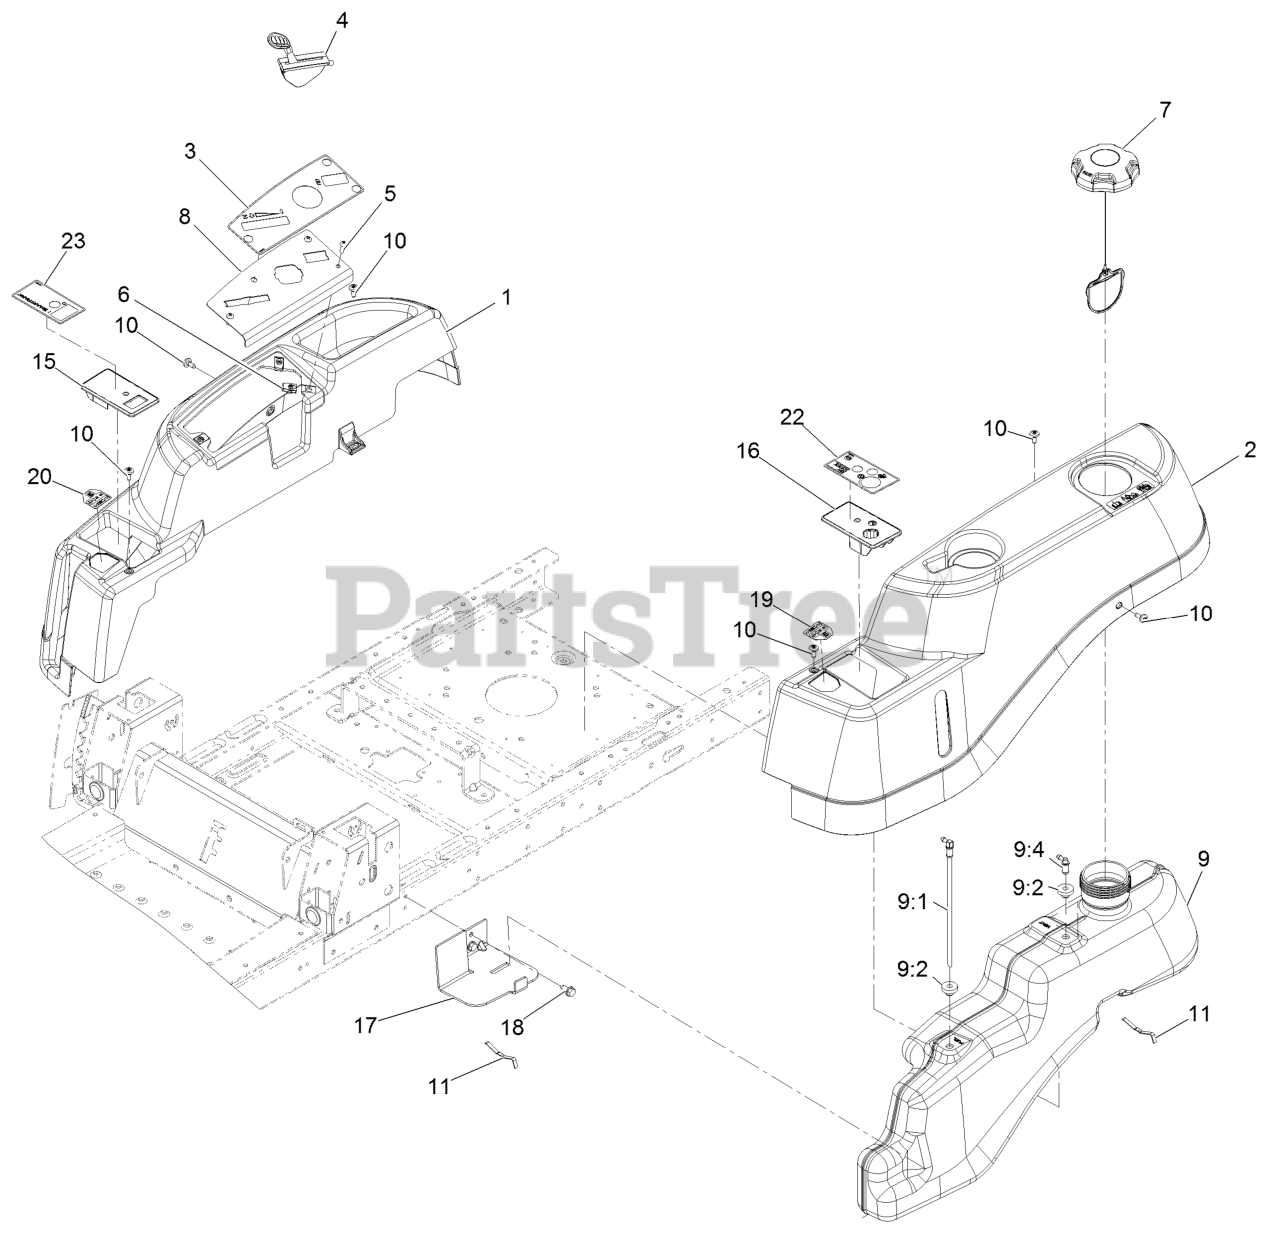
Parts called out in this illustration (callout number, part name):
3	DECAL-PANEL, CONTROL
4	CABLE-THROTTLE
5	SCREW-PRH
6	Nut-Retainer-Panel 1/4-20
8	PLATE-CONTROL
9	FUEL TANK ASM
9:1	CONNECTOR-ELBOW, 90 DEG
9:2	BUSHING
9:4	FITTING-PLASTIC
10	SCREW-SHOULDER
11	SPRING
15	COVER-RH
16	COVER-LH
17	SUPPORT-TANK, FRONT
18	Screw-HWH 5/16-18 X 3/4 Tf
19	DECAL-NMIR
20	DECAL-CONTROL, PEDAL
22	DECAL-KEYCHOICE
23	DECAL-BRAKE, PARKING
